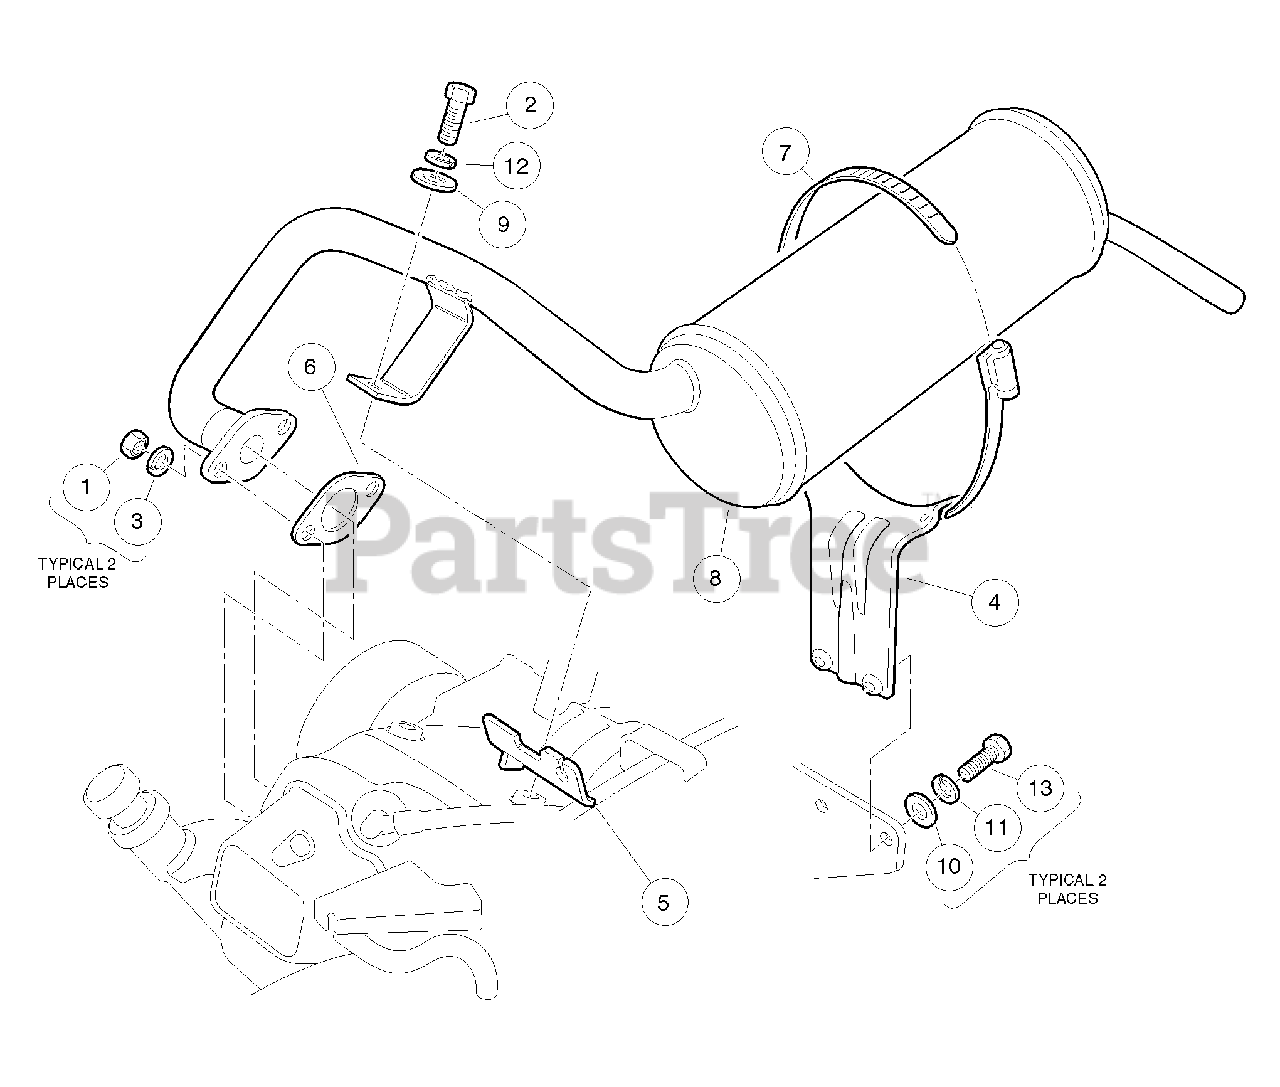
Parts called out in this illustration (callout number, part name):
1	Nut, M8-1.25 Hex
2	Screw, M8-125 X 22 Hex-Head
3	Lockwasher, 8mm Split
4	Bracket, Muffler Mounting
5	Bracket, Governor Cable Snap-In
6	Gasket, Exhaust
7	Clamp, 5" Muffler Hose
8	Exhaust System
9	Washer, 5/16 Type A Flat
10	Washer, 1/4 Type A Narrow Flat
11	Lockwasher, 1/4 Helical Split
12	Lockwasher, 5/16 Split
13	Screw, 1/4-20 X 0.75 Hex-Head Cap
